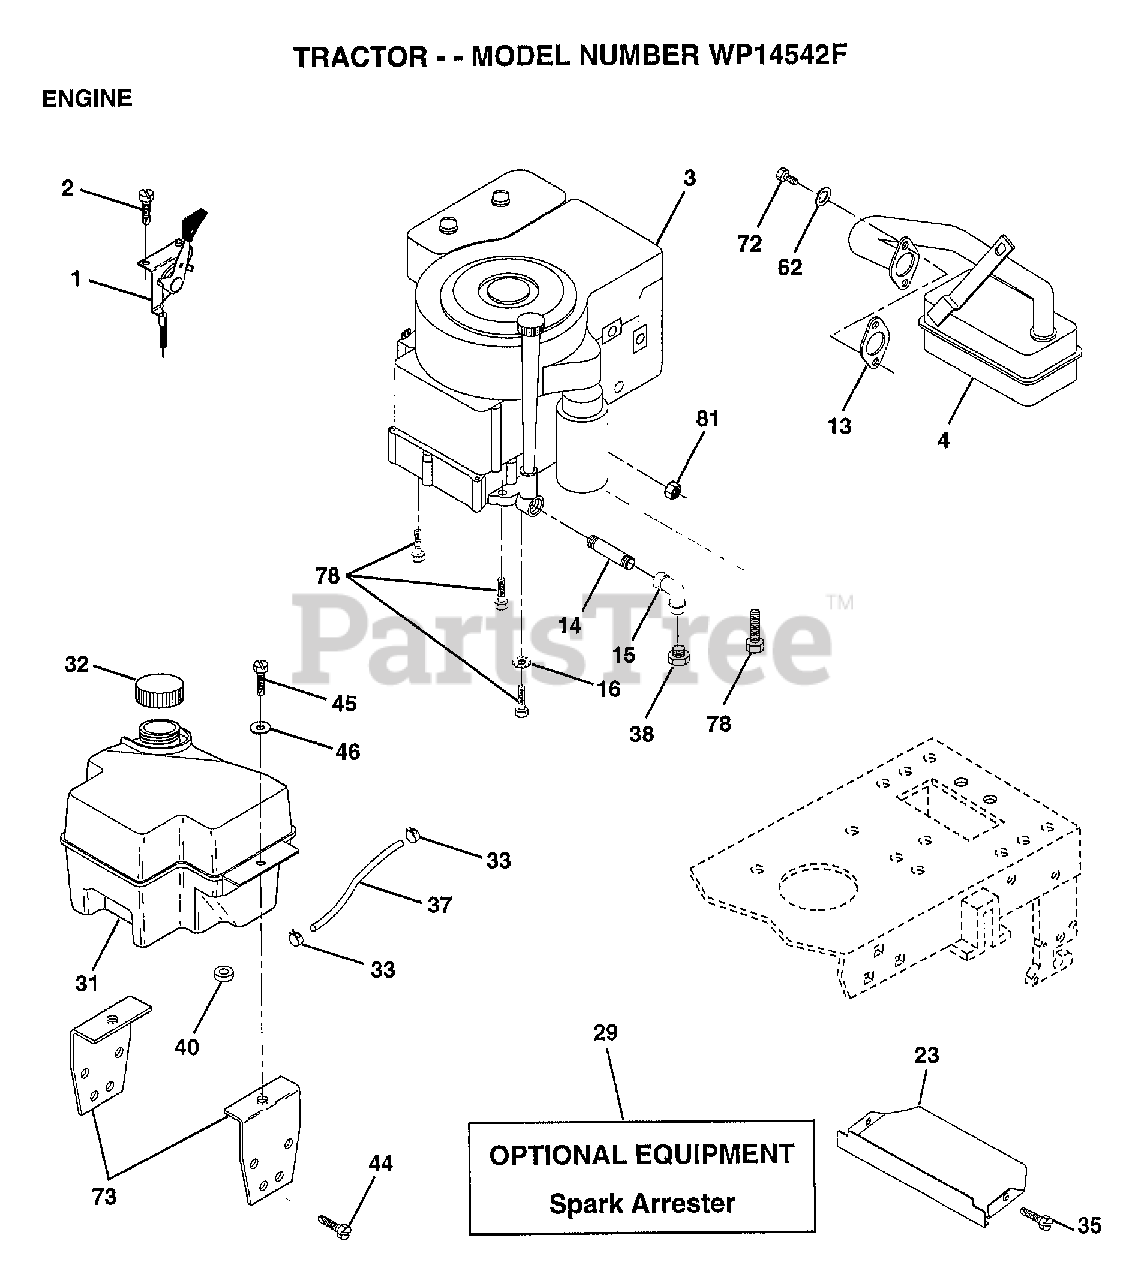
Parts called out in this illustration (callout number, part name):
1	"CONTROL,THROTTLE"
2	SCREW LT
4	MUFFLER
14	PIPE NIPPLE
15	ELBOW
16	LOCKWASHER
23	SHIELD.BRN/DBR.GD
31	TANK.FUEL.FRONT.
32	CAP ASM FUEL
33	HOSE CLAMP
35	SCREW
37	LINE FUEL
44	SCREW
45	SCREW HEX CRT
46	WASHER
62	LOCKWASHER
72	SCREW
73	BRACKET.SUPT.TANK
78	SCREW
81	NUT
